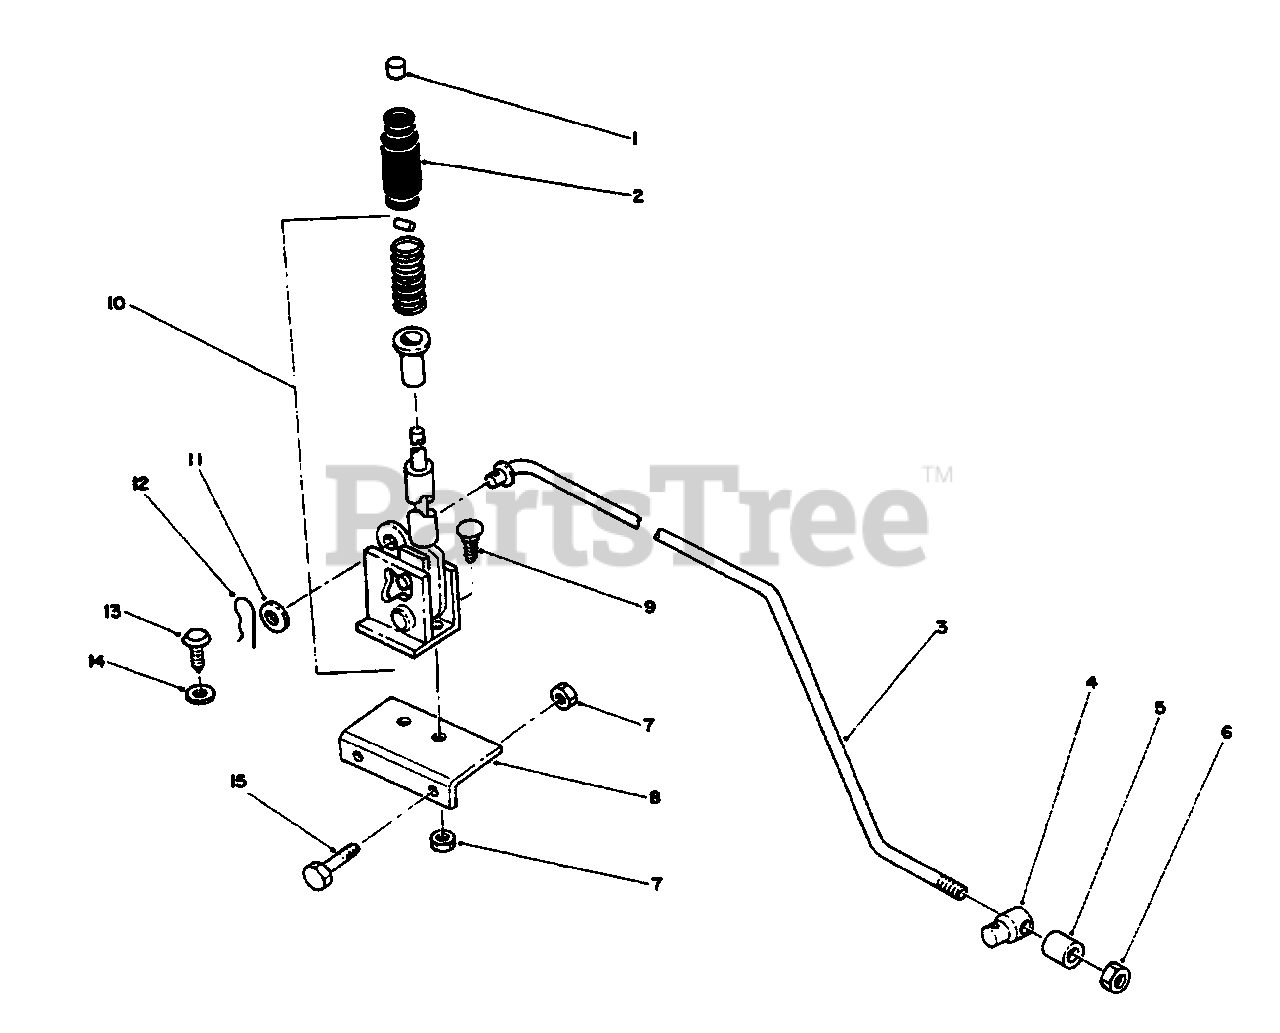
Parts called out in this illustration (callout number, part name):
3	Rod-Lift
4	Trunnion
5	Spacer
6	Nut-Lock
7	Nut-Lock
8	Bracket-Support
9	Bolt-Carriage
10	Handle-Lift
11	Washer-Flat
12	Cotter-Hairpin
13	Fastener-Footpad
14	Washer-Flat
15	Screw-Hex Hd. Cap
